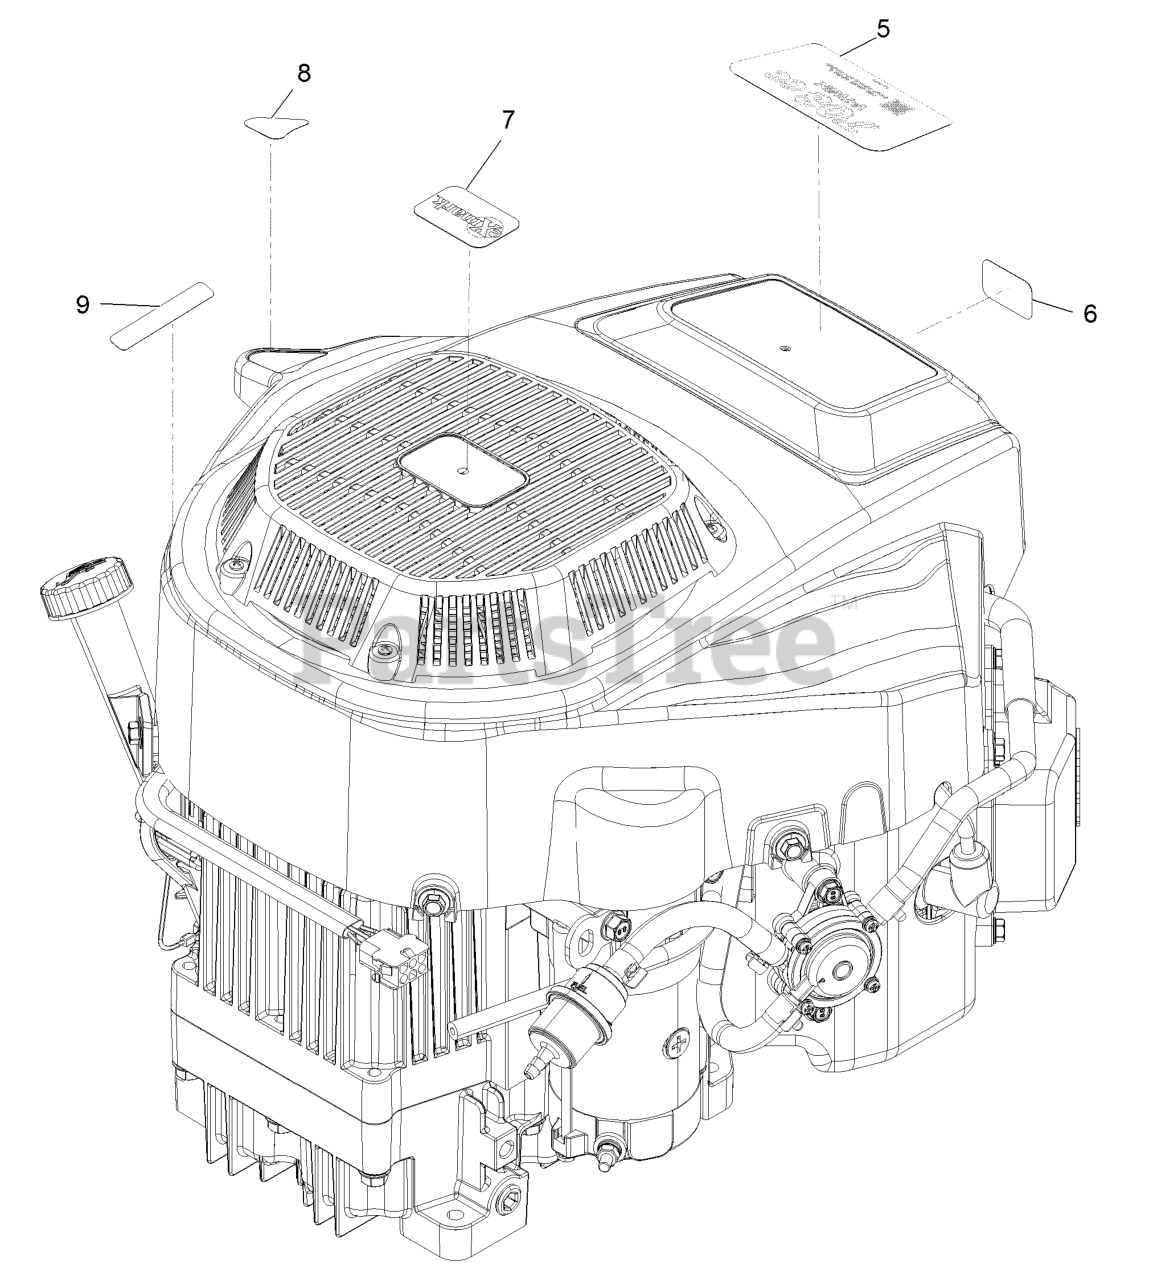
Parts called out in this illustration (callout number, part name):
5	Decal-Engine Displacement
6	Placard-Intake, Exmark
8	Decal-Drain, Oil
9	Decal-Shutdown
